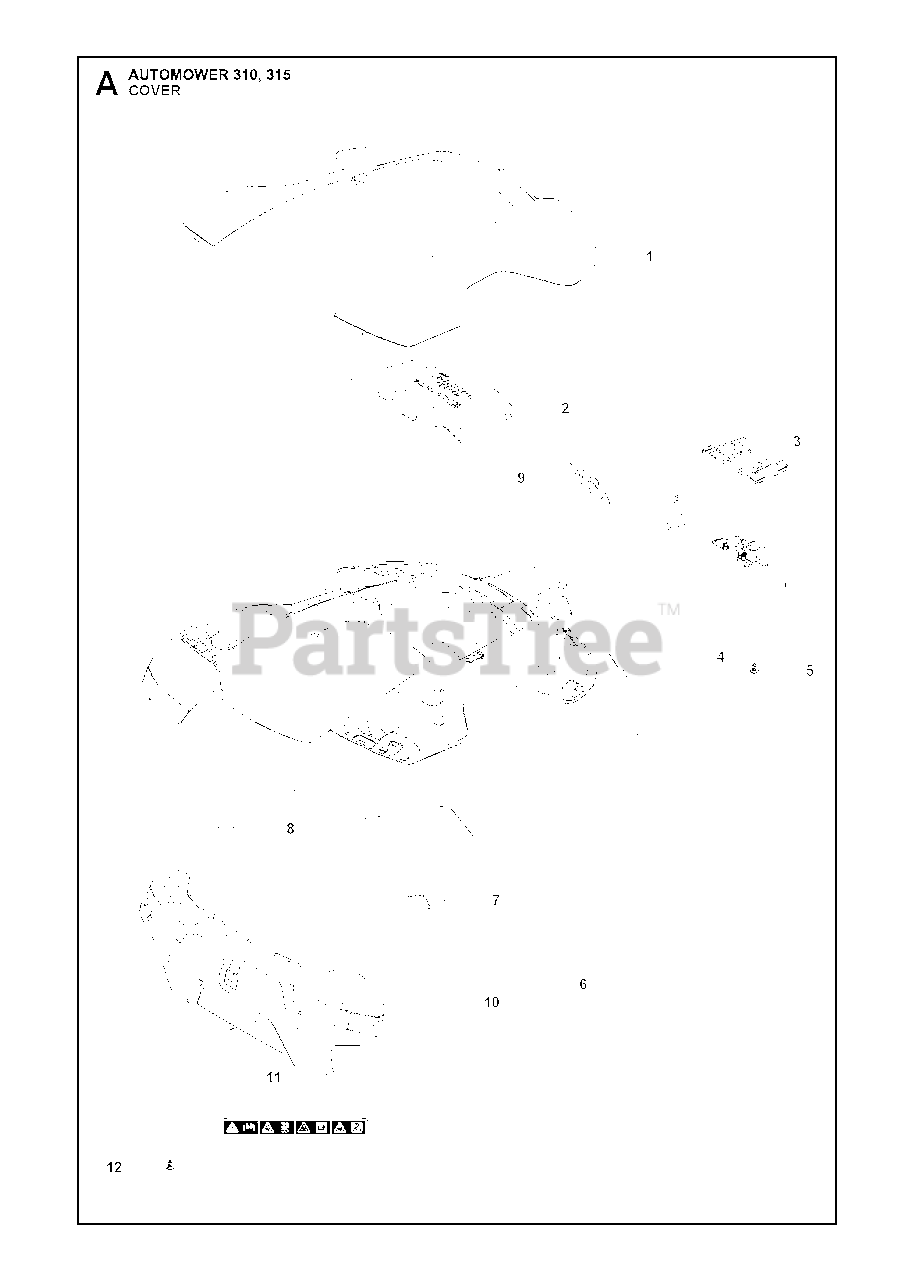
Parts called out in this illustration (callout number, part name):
1	GREY COVER
1	Cover, White
1	ORANGE COVER
2	HOOD 310
2	HOOD 315
3	LOOM CHARGING PLATE
4	HOLDER KIT
5	SCREW ITXPANT
6	BODY KIT
7	SPRING HOOD
8	CAP SNAPLOC
9	DECAL HUSQVARNA CROWN HEIGHT 5
10	BUMPER KIT
11	LABEL WARNING P15
12	SCREW ITXPANT
